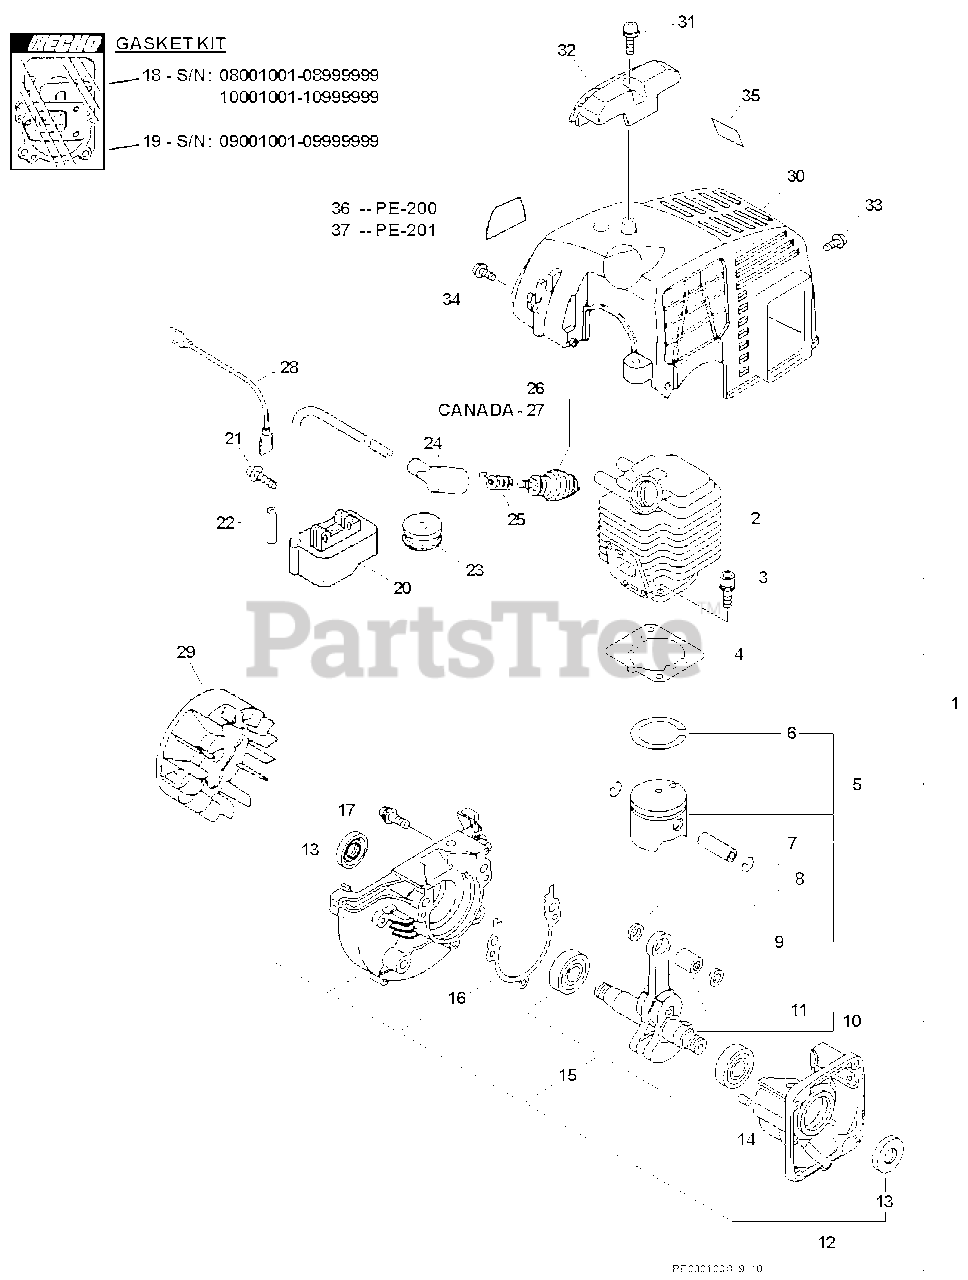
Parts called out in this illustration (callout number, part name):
1	SHORT BLOCK -- SB1072
2	CYLINDER
3	SCREW - 5X22
4	GASKET, CYLINDER
5	PISTON KIT
6	RING, PISTON
7	PIN, PISTON
8	RING, RETAINING
9	SPACER, PISTON
10	CRANKSHAFT ASSY
11	BEARING, NEEDLE - 8
12	CRANKCASE KIT
13	SEAL, OIL
14	PIN - LOCATING
15	BEARING, BALL - 6201
16	GASKET, CRANKCASE
17	SCREW - 5X28
18	GASKET KIT
19	GASKET KIT
20	COIL, IGNITION
21	SCREW - 4X20
22	TUBE, INSULATOR
23	GROMMET
24	CAP, SPARK PLUG
25	TERMINAL, SPARK PLUG CAP
26	SPARK PLUG -- BPM-8Y
27	SPARK PLUG -- BPMR-8Y
28	LEAD - GROUND
29	FLYWHEEL
30	COVER, ENGINE
31	SCREW - 5X16 -- TAPPING
32	GUARD - TOP
33	SCREW - 4X8
34	SCREW - 4X12 -- TAPPING
35	LABEL - HOT SURFACE
36	LABEL - MODEL PE-200
37	LABEL - MODEL PE-201
